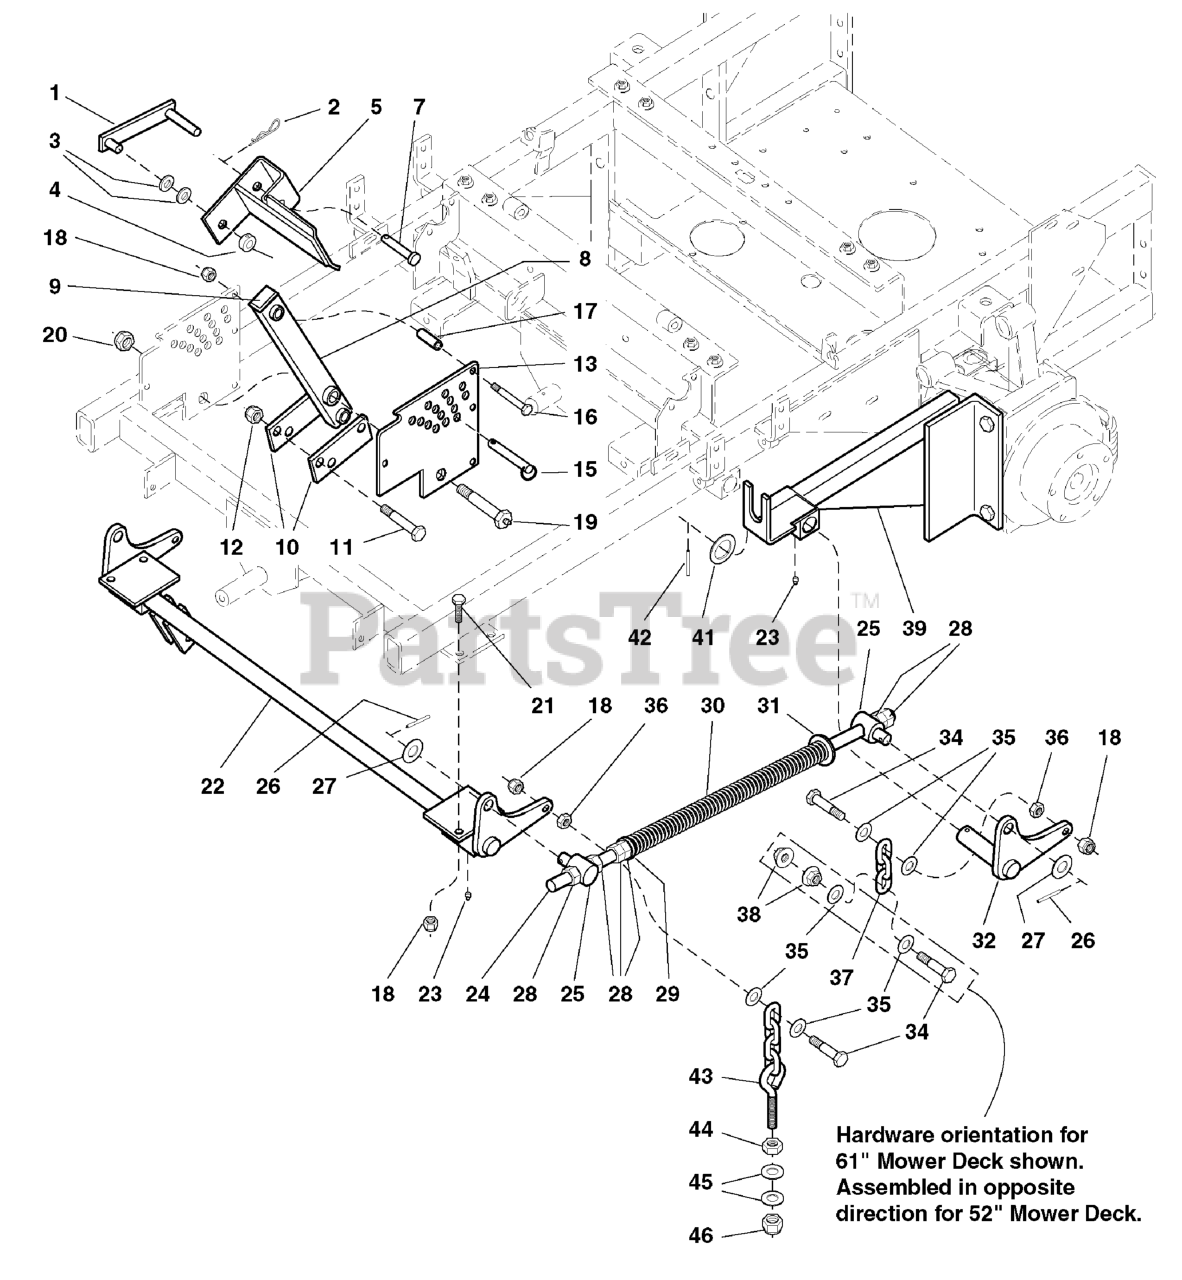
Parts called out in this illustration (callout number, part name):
1	DECK LIFT LOCK
2	HAIRPIN CLIP
3	WASHER, 1/2 SAE
4	COLLAR, 1/2" Set
5	WELD, DECK LIFT PEDAL
7	PIN, Clevis, 1/2 x 2-1/2
8	ARM, Deck Lift Pivot
10	DECK LIFT LINK
11	BOLT, 1/2-20 x 3
12	NUT, Hex, Nylon Lock, 1/2-20
13	DECK HEIGHT PLATE
15	PIN, 1/2 x 3
16	BOLT, 3/8-16 X 2-3/4" GD5 CZ
17	SPACER, .38 x .50 x 1.56
18	NUT, 3/8-16 HEX NYLON LOCK
19	LIFT PIVOT BOLT
20	NUT, 5/8-11 Hex Jam Nylon Lock
21	BOLT, 3/8-16 X 1-1/4" GD5 CZ
22	DECK LIFT SHAFT & MOUNT ASSEMBLY
23	GREASE FITTING
24	SPRING ROD
25	SPRING ROD PIVOT
26	PIN, Spring, 3/16 x 1-1/4
27	WASHER, 5/8" SAE
28	NUT, 5/8-11 Hex
29	SPACER, .63 x 1.06 x .23
30	SPRING, Deck Lift
31	WASHER, 5/8" USS
32	DECK LIFT PIVOT - LH
34	BOLT, 3/8-16 X 1-3/4" GD5 CZ
35	WASHER, 3/8 SAE
36	NUT, 3/8-16 HEX JAM
37	CHAIN, 6 LINKS
38	NUT, 3/8-16 Hex Serrated Flange
39	REAR DECK LIFT FRAME - LH
42	PIN, Roll, 3/16 x 1-1/2
43	HANGER, FRONT DECK - 4 LINK, 5.5" EB
44	NUT, 1/2-13 Hex
45	WASHER, 1/2 SAE
46	NUT, 1/2-13 HEX NYLON LOCK
